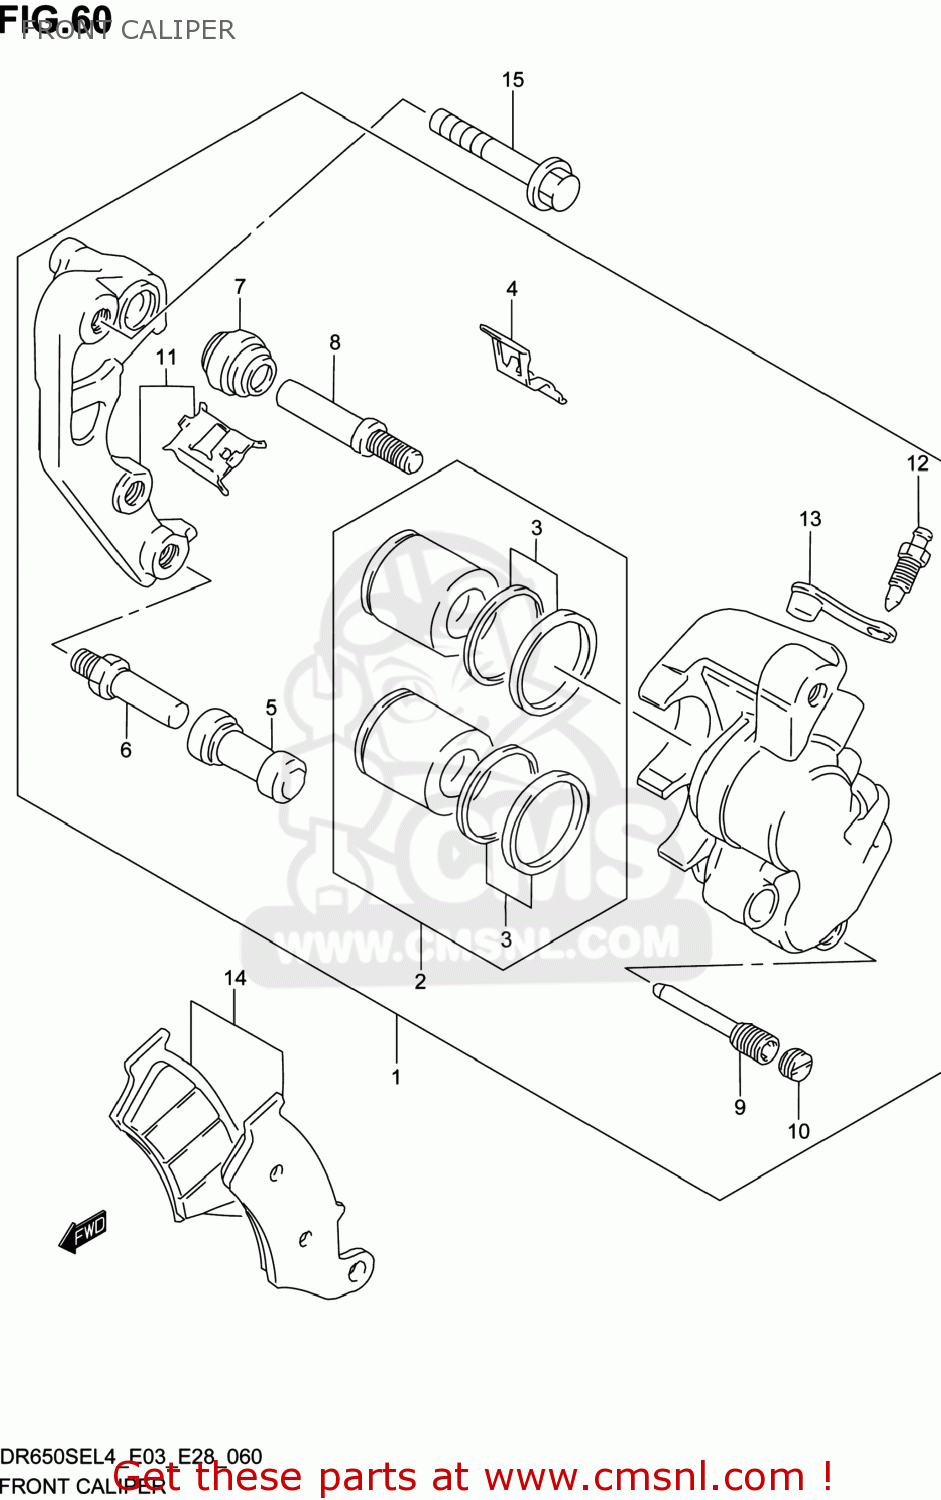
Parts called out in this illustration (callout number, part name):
1	CALIPER ASSY,FR,L
2	PISTON SET
3	SEAL SET,PISTON
4	SPRING,PAD
5	BOOT
6	PIN,BOLT
7	BOOT
8	PIN
9	PIN,HANGER
10	PLUG,PIN
11	BRACKET
12	BLEEDER
13	CAP,BLEEDER
14	PAD SET (NAS)
15	BOLT(8X40)
